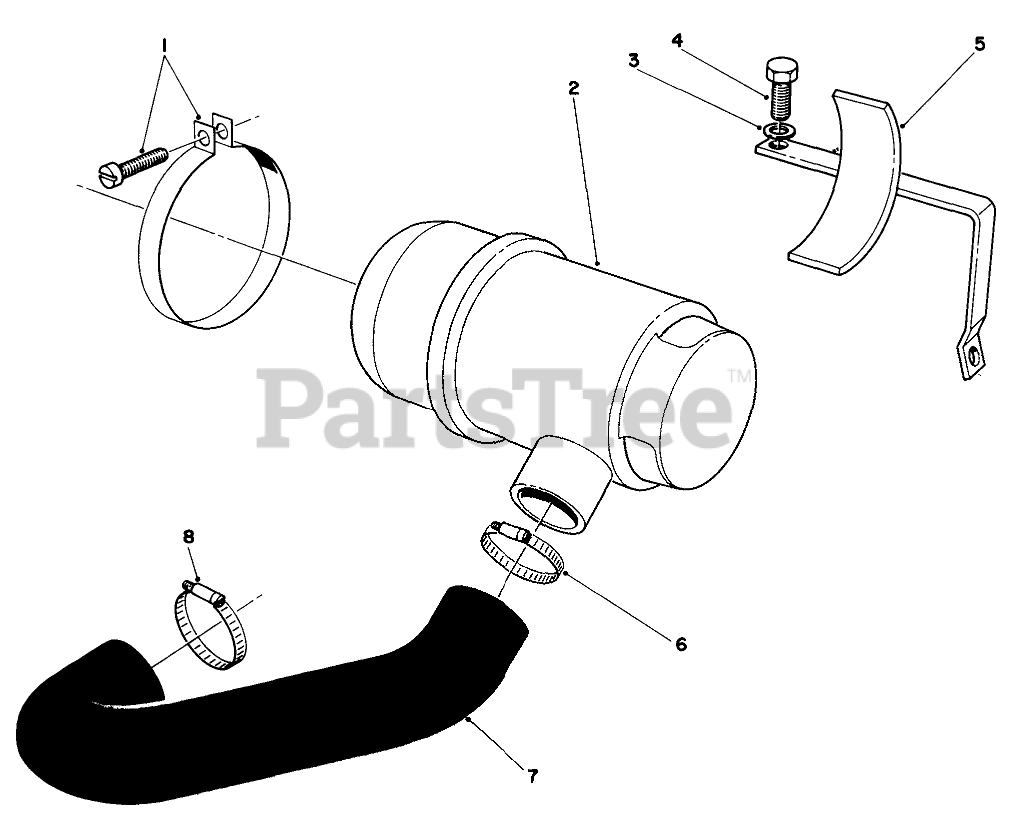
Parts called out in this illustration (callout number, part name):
1	Tension Clamp
2	Oil Bath Air Filter
3	Lockwasher
4	Screw-Hex Head
5	Support
6	Clamp-Tension
8	Clamp-Tension
